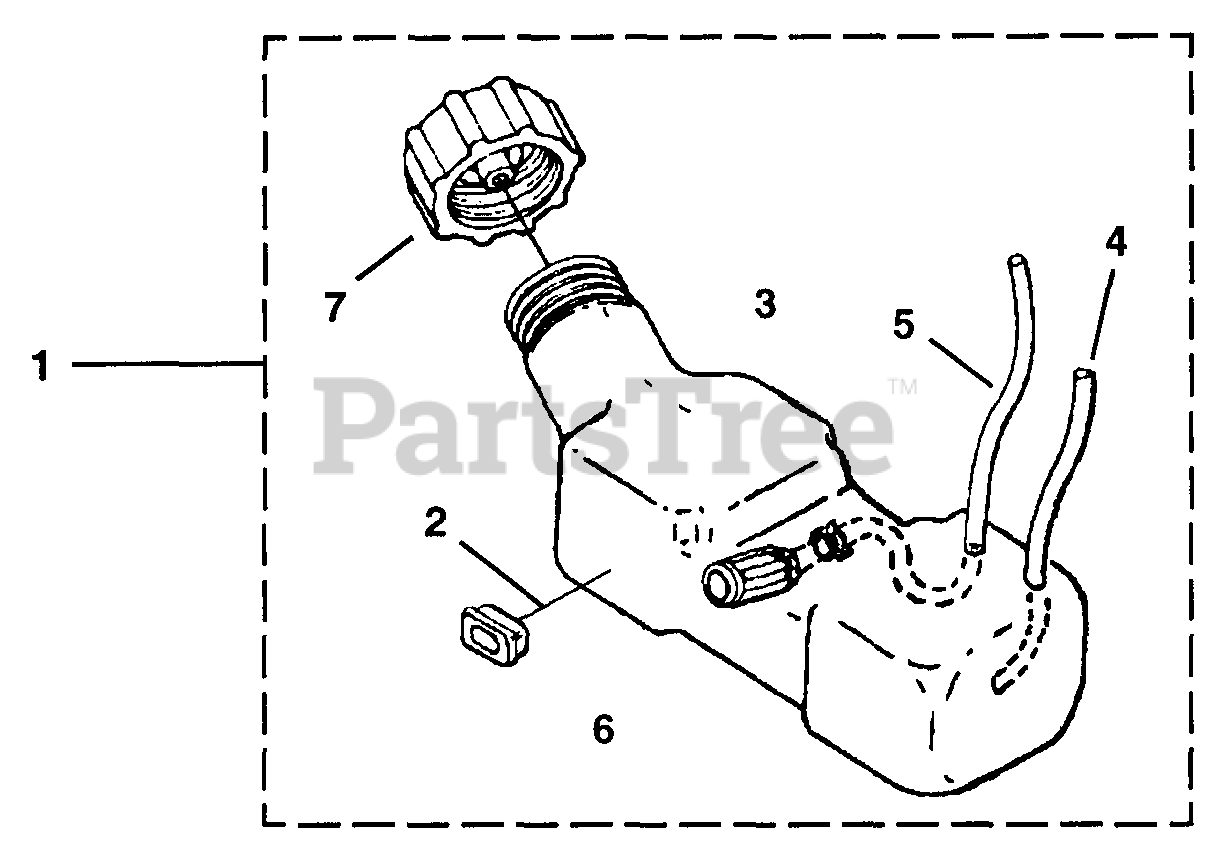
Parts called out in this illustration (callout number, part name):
1	FUEL TANK ASSY.
2	BUMPER, RUBBER
3	CLAMP, FUEL LINE
4	TUBBING, FUEL
5	TUBBING, FUEL
6	FUEL FILTER
7	FUEL CAP
